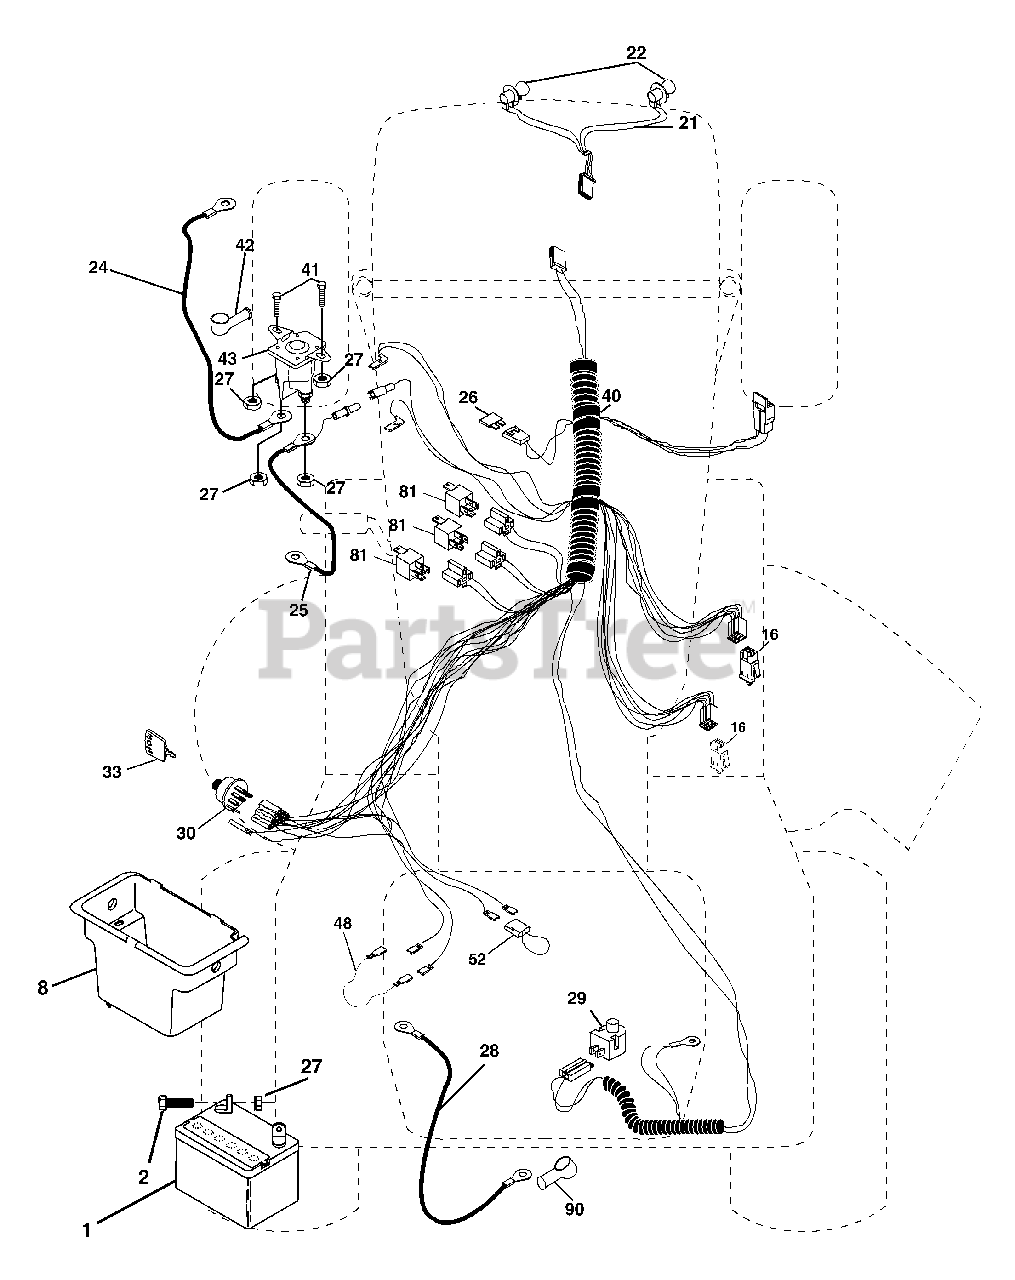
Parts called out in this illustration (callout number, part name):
1	Battery
2	Bolt Hex Hd 1/4-20unc X 3/4
8	Box Battery
16	Switch Interlock
21	Harness Asm Light W/4152j
22	Bulb Light #1156
24	Cable Battery 6 Ga 11" red
25	Cable Battery 6 Ga 44" red w/16 wire
27	Nut Keps Hex 1/4-20 Unc
28	Cable Ground 6 Ga 12" black
29	Switch Plunger Olive
30	Switch Ign Delta
33	Key Ign Molded Generic
40	Harness Ign.
41	Bolt Blk Fin Hex 1/4 - 20 x 1/2
42	Cover Terminal Red
43	Solenoid
48	Adapter Ammeter Rectangular
52	Protection Wire Loop
81	Relay Asm.
90	Cover Terminal Battery
